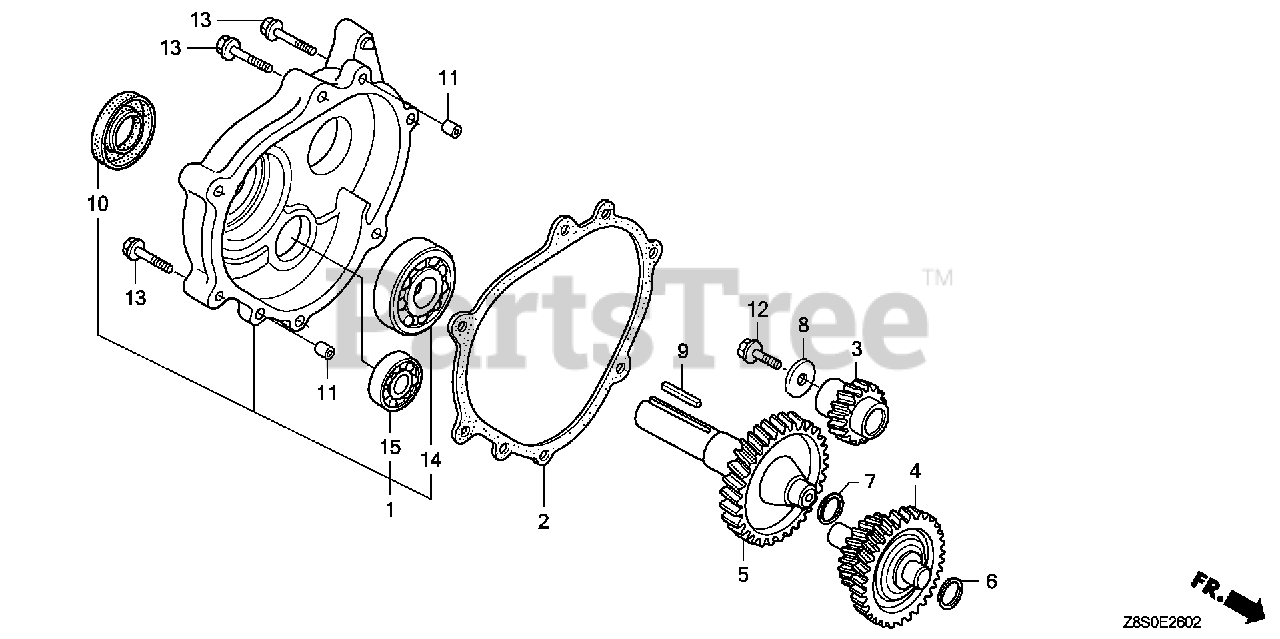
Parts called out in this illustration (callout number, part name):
1	COVER ASSY., REDUCTION CASE
2	GASKET, CHAIN CASE COVER
3	GEAR, PRIMARY DRIVE (17T)
4	COUNTERSHAFT (18T/40T)
5	SHAFT, P.T.O. (46T)
8	WASHER (8MM)
9	KEY (6.3X6.3X43)
10	OIL SEAL (30X46X8) (NOK ASIA)
11	PIN, DOWEL (8X14)
12	BOLT, FLANGE (8X25)
13	BOLT, FLANGE (8X40)
14	BEARING, RADIAL BALL (6206)
15	BEARING, RADIAL BALL (6302)
